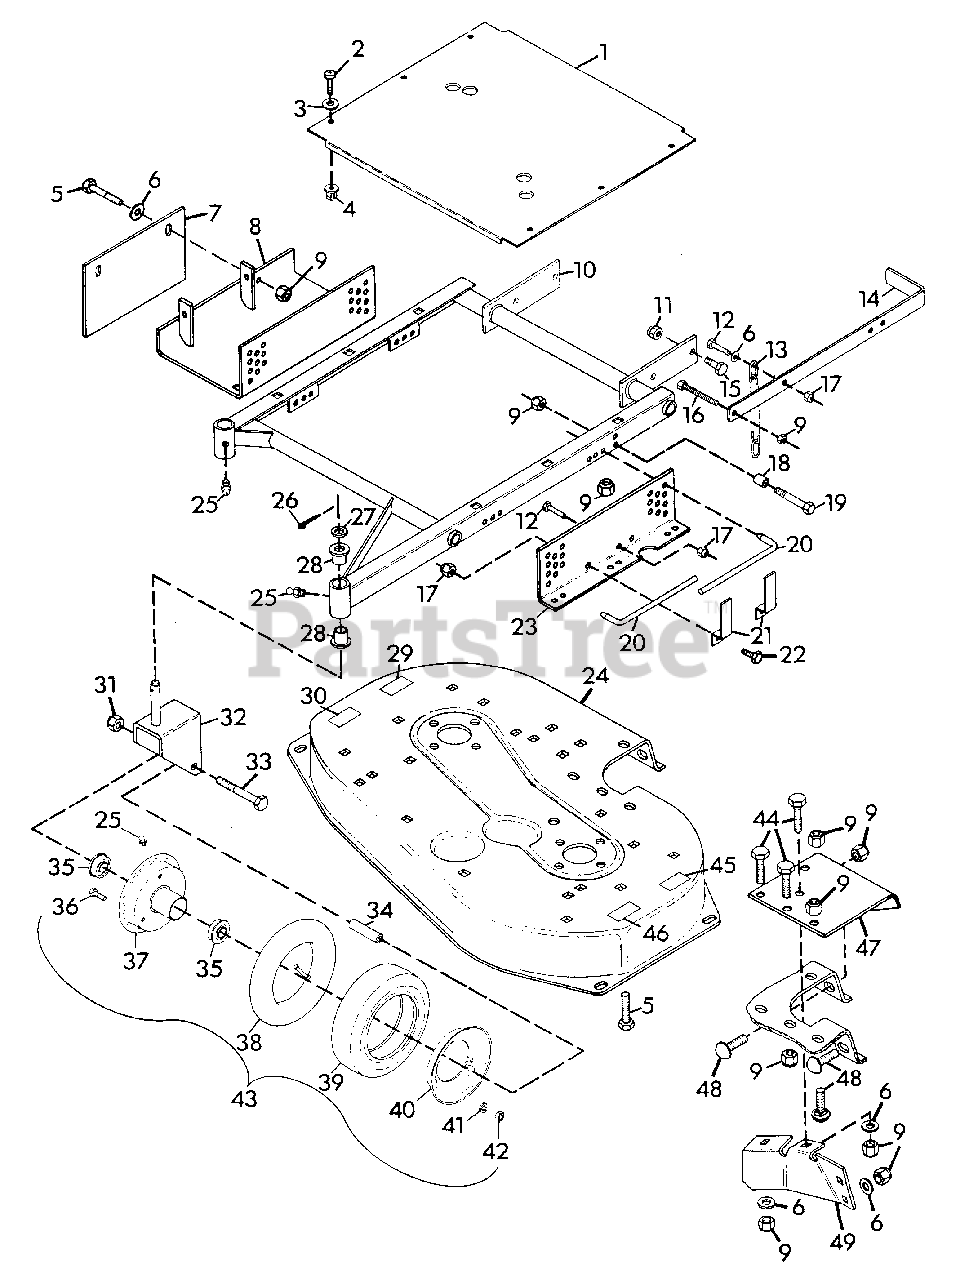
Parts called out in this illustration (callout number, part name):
1	GUARD, MOWER BELT
2	SCREW, TAPPING 1/4-20X.625 P/HD
3	WASHER, FLAT .281X.625X.065
4	GROMMET, PLASTIC
5	BOLT, HEX 3/8-16X1.00
6	WASHER, FLAT .406X.812X.065
7	PLATE, DISCHARGE COVER
8	WELDMENT, MOWER SUPPORT
9	NUT, LOCK 3/8-16
10	WELDMENT, MOWER FRAME
11	NUT, LOCK 5/8-11
12	BOLT, HEX 5/16-18X1.00
13	CHAIN, HEIGHT ADJUSTMENT
14	BAR, LIFT
15	BOLT, HEX 5/8-11X1.50
16	BOLT, HEX 3/8-16X2.00
17	NUT, LOCK 5/16-18
18	BUSHING .391X.622X.670
19	BOLT, HEX 3/8-16X1.50
20	PIN, MOWER LOCKING
21	TAB, PIN LOCKING
22	BOLT, HEX 5/16-18X.75
23	BRACKET, MOWER SUPPORT
24	DECK, 40" MOWER
25	FITTING, LUBE 1/4-28
26	PIN, COTTER .187X1.50
27	RACE, BEARING THRUST
28	BUSHING, PIVOT
29	DECAL, CAUTION
30	DECAL, DANGER FOOT
31	NUT, LOCK 1/2-13
32	WELDMENT, CASTER FORK
33	BOLT, HEX 1/2-13X5.00
34	BUSHING, WHEEL .520X.750X3.312
35	BEARING, GAUGE WHEEL
36	BOLT, HEX 3/8-24X.75
37	WHEEL, HALF WITH TUBE
38	TUBE, INNER
39	TIRE, GAUGE WHEEL
40	WHEEL, HALF PLAIN
41	WASHER, LOCK 3/8 SP HEAVY
42	NUT, HEX 3/8-24
43	WHEEL, GAUGE
44	BOLT, HEX 3/8-16X1.25
45	DECAL, WARNING EYE
46	DECAL, DANGER HAND
47	SHIELD, DISCHARGE
48	BOLT, 3/8-16X1.00 RD HD SQ NK
49	SHROUD, BLADE
NS	DECAL, GRAVELY LOGO
NS	DECAL, PRO-40
